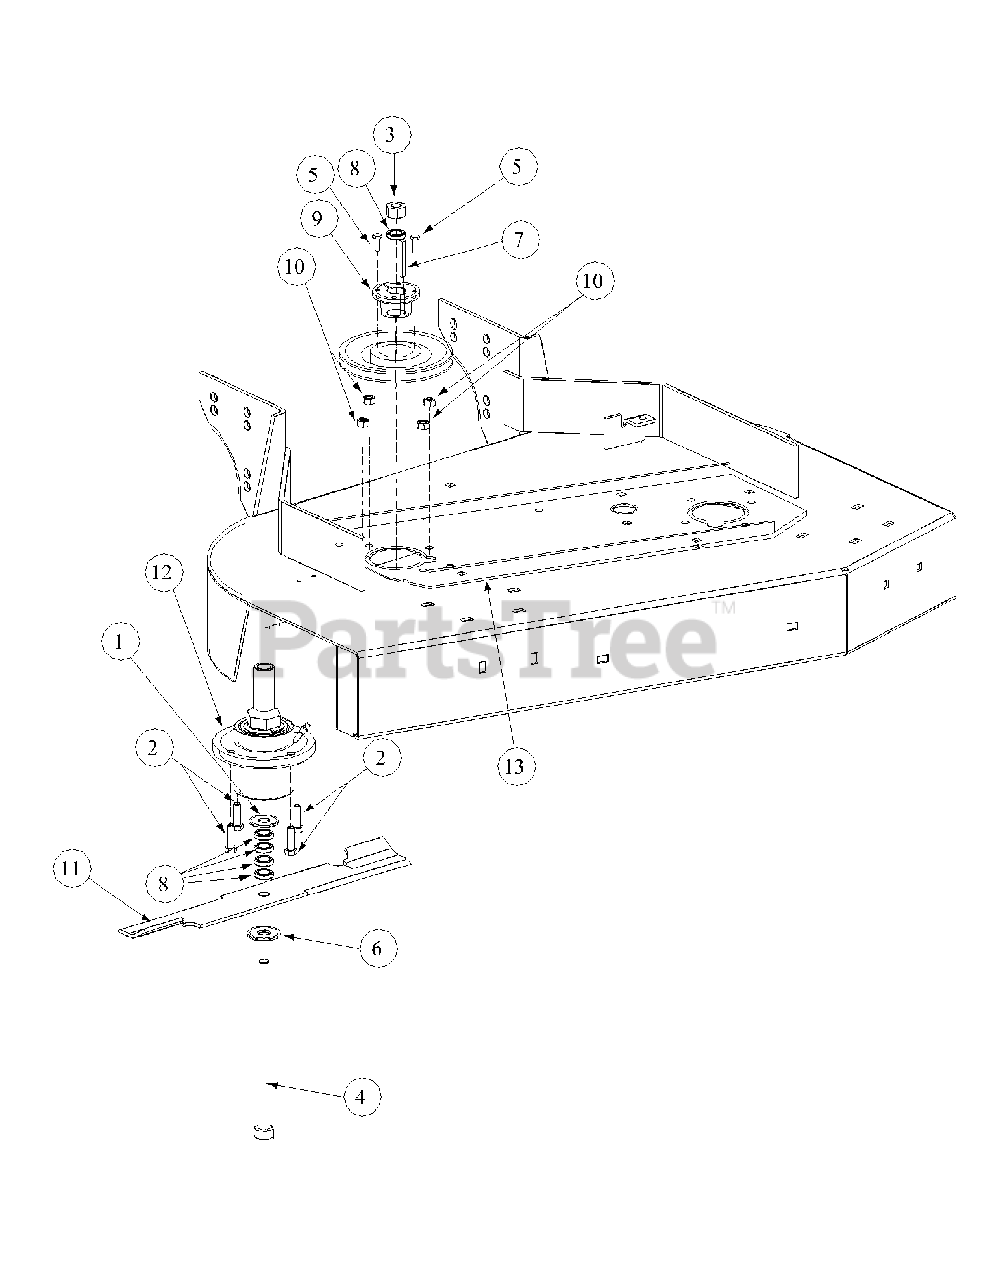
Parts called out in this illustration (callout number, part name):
1	Flat Washer, 1-1/2 x 5/8 x .05
2	Hex Cap Screw, 3/8-16 x 1-1/4
3	Hex Nut, 5/8-11
4	Hex Cap Screw, 5/8-11 x 9-1/2
5	Hex Cap Screw, 1/4-20, .75
6	Flat Washer, 5/8 Zinc
7	Key Stock, 1/4 x 1/4 x 2
8	Blade Spacer, 5/8 ID, 1/4 Thick
10	Lock Nut, 3/8-16
11	Blade 18"
12	Spindle Assembly
13	Deck Stiffener
